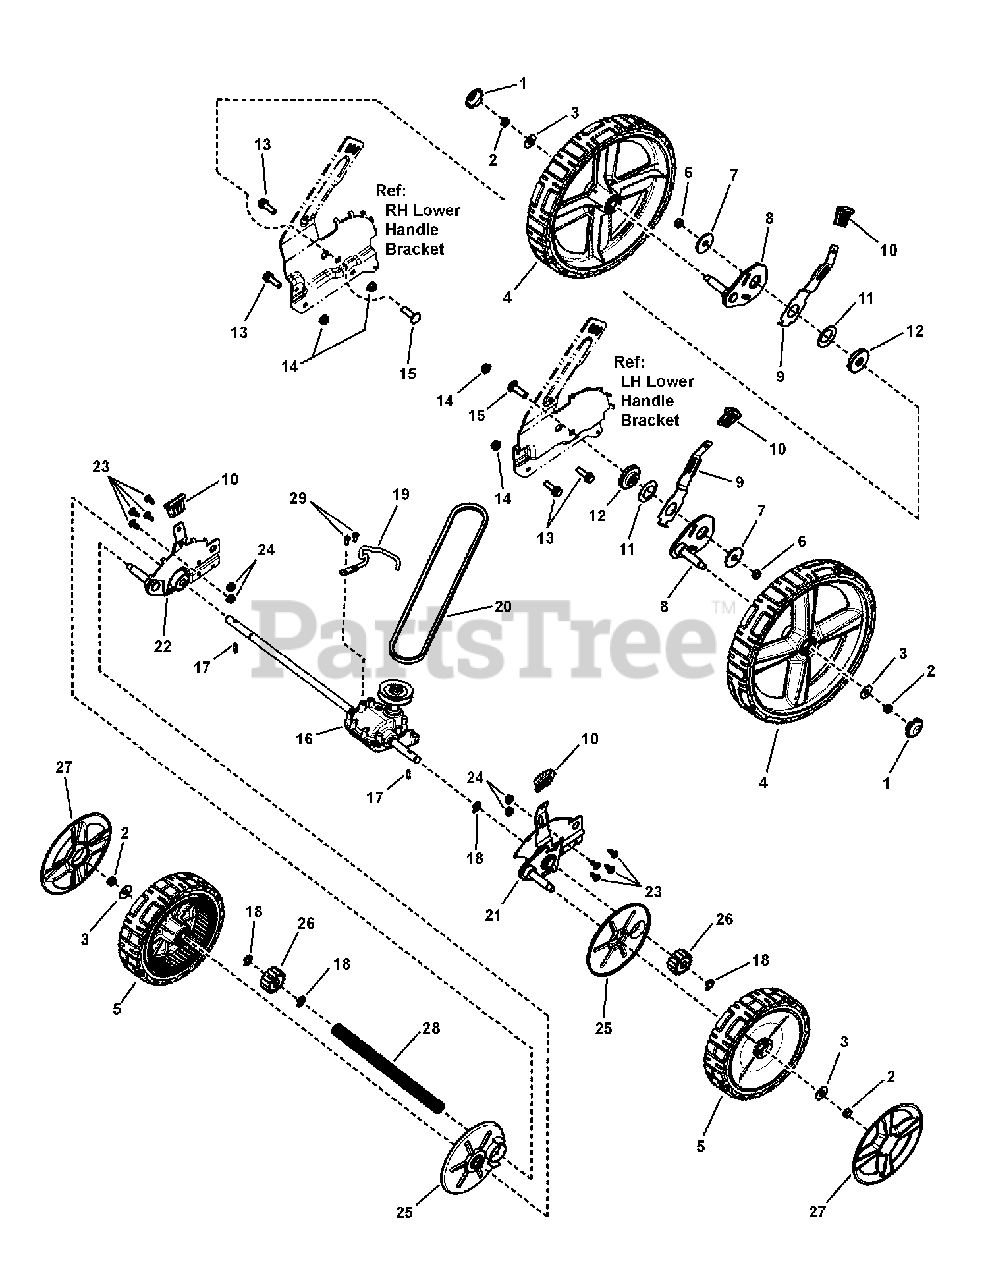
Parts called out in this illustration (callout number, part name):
1	HUBCAP, 12" Wheel, Snapper Cool Gray
2	NUT, 3/8-16 Hex Center Lock, GR 5, YZ
3	WASHER, 1" O.D. x .387 I.D., Flat
4	ASSEMBLY, Wheel, 12" x 2" w/Snapper Tread, Cool Gray
5	ASSEMBLY, Wheel, 8" x 2" Drive w/Snapper Tread, Charcoal Gray
6	JAM NUT, 3/8-16 Hex Center Lock
7	WASHER, 13/32 x 1-1/2" x .120 Flat, YZ
8	ASSEMBLY, Rear Wheel Bracket, Hi-Wheel (staked)
9	LEVER, Front, Height-Of-Cut, 22"
10	GRIP, Height Latch - Black (1.7" Wide)
11	WASHER, Belleville, 1.01-1.64
12	BUSHING, Pivot, Hi-Wheel, Rear
13	BOLT, 5/16-18 x 1" Hex Flange lock, GR 5, YZ
14	NUT, 5/16-18 Hex Flange Lock, GR 5, YZ
15	BOLT, 3/8-16 x 1-1/4" Round Head Square Neck Carriage, GR 5 YZ
16	TRANSMISSION, Variable Speed, Front Wheel Drive
17	DRIVE PIN, 22" WBM
18	RETAINING RING
19	GUIDE, Belt, FWD
20	BELT, 3L, Traction Drive, 22" WBM, FWD
21	ASSEMBLY, Height-of-Cut, LF, 22" WBM, Propelled
22	ASSEMBLY, Height-of-Cut, RF, 22" WBM, Propelled
23	SCREW, 1/4-20 x .550" Pan Head Self-Tap (Torx)
24	NUT, 1/4-20 Hex Flange Lock, YZ
25	SHIELD, Dust, 22" WBM, Front Wheel Drive
26	GEAR, Pinion, 22" WBM, Front Wheel Drive
27	HUBCAP, 8" & 9" Spoked Wheel, Snapper Cool Gray
28	SHIELD, Axle
29	SCREW, #10-14 x 1/2" Hex Washer Self-Tap, Plastite
